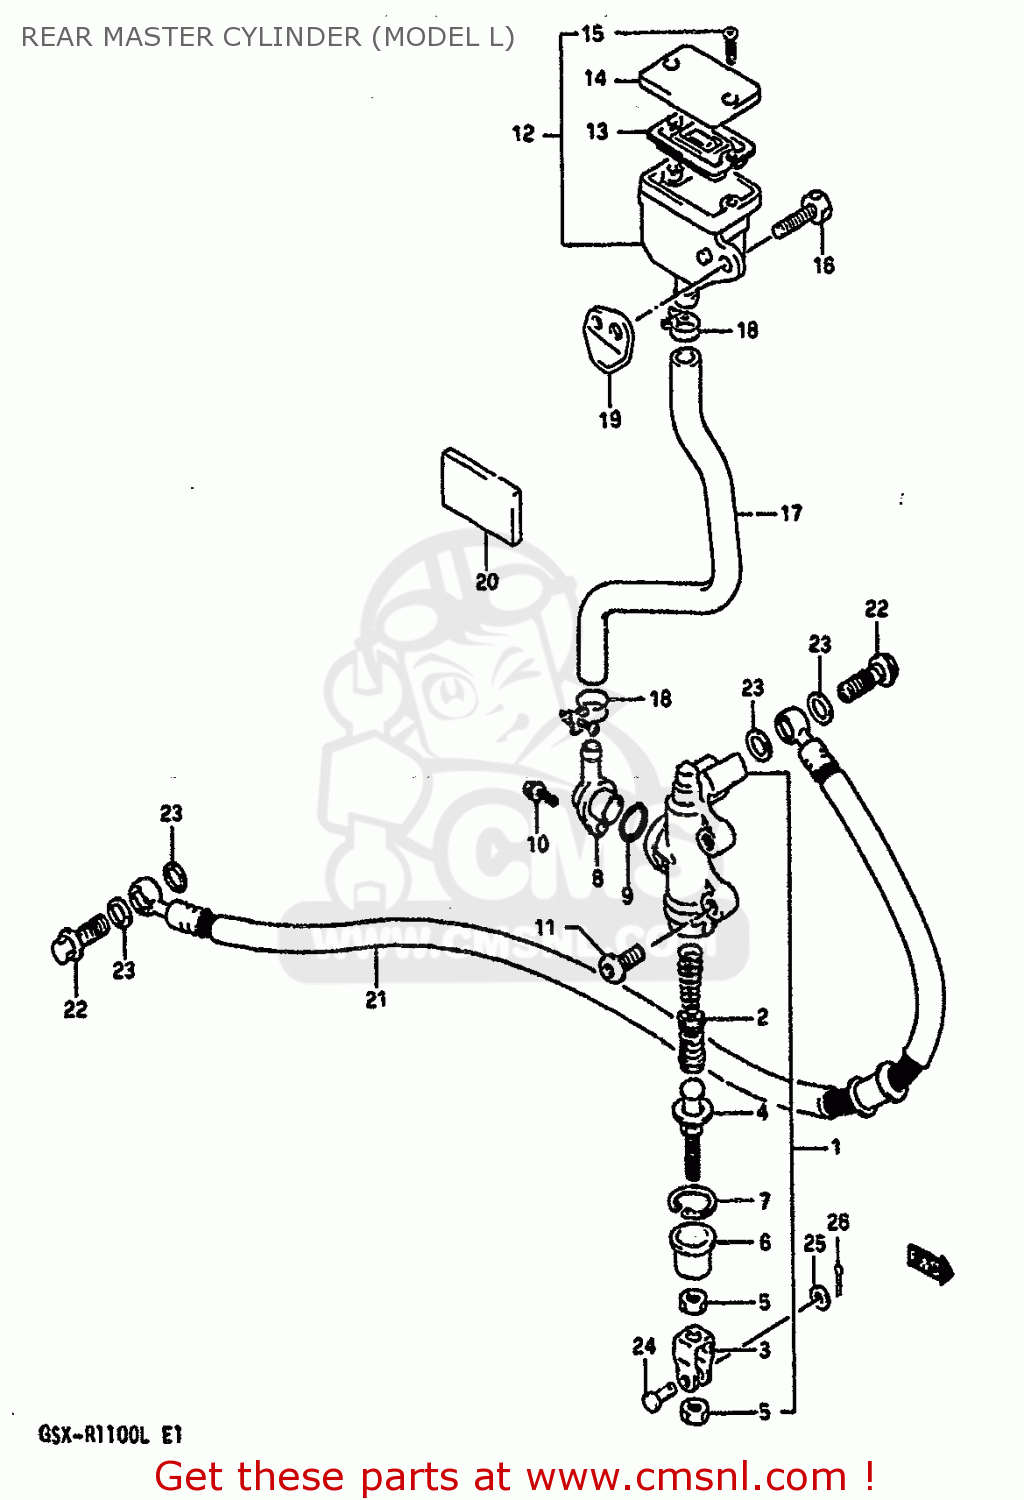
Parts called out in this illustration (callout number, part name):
1	CYLINDER ASSY,RR MASTER
2	PISTON/CUP SET
3	YOKE
4	ROD,PUSH
5	NUT
6	BOOT
7	CIRCLIP
8	CONNECTOR
9	O RING
10	SCREW
11	SCREW(8X22)
12	TANK ASSEMBLY,RESERVOIR
13	DIAPHRAGM
14	CAP
15	SCREW
16	BOLT
17	HOSE,RESERVOIR TANK
18	CLAMP
19	BRACKET,RESERVOIR TANK RR
20	CUSHION,PANEL
21	HOSE,REAR BRAKE
22	BOLT UNION
23	WASHER(10X15X1.5)
24	PIN
25	WASHER
26	PIN
27	WASHER
28	PIN
